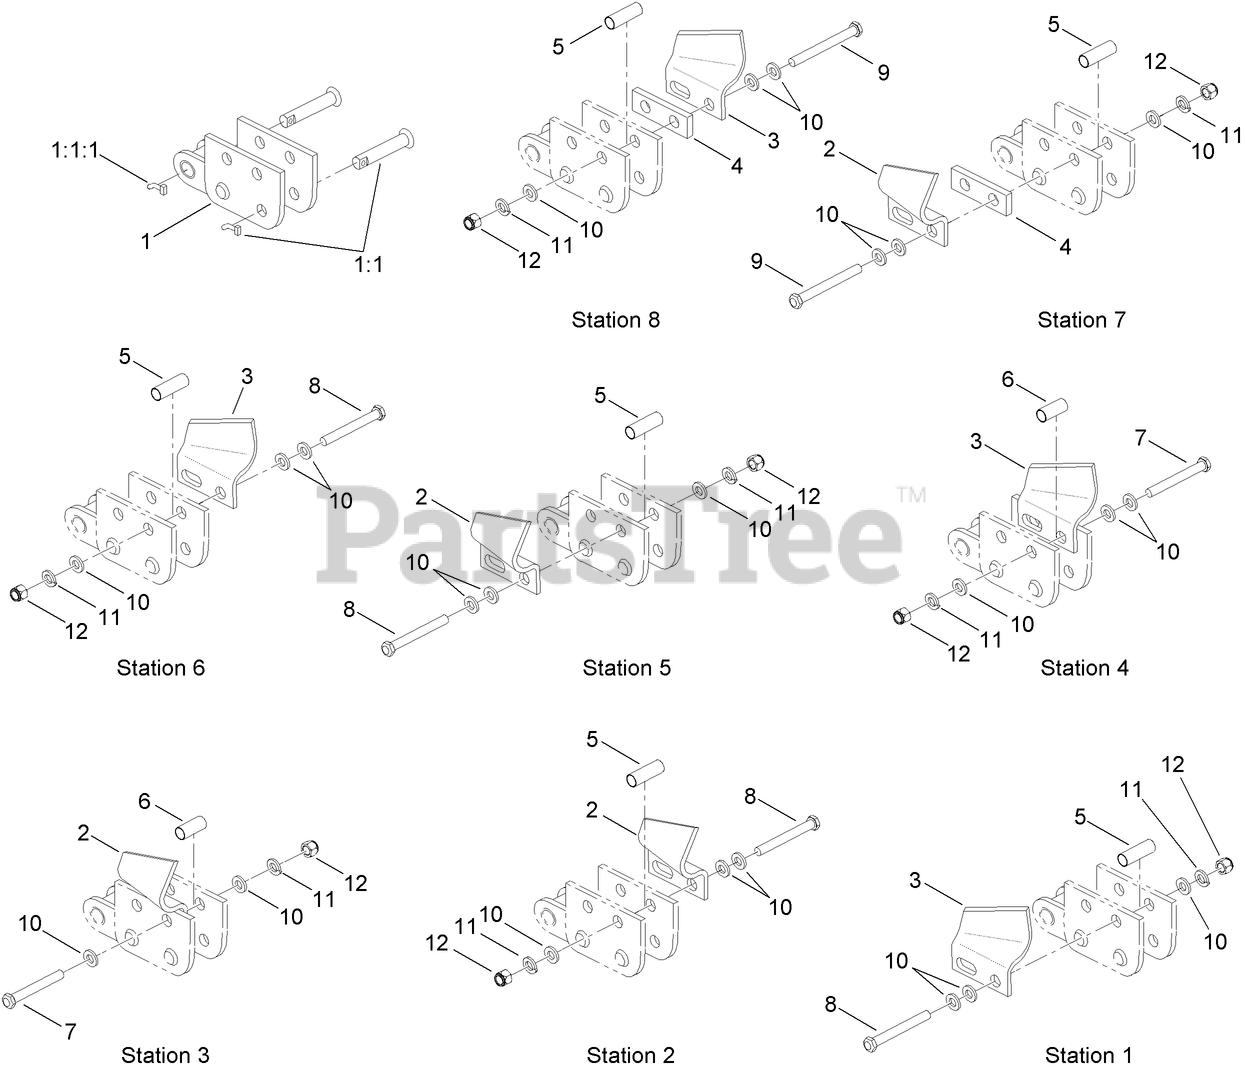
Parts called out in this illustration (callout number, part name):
1	CHAIN REPAIR LINK ASM
1:1	NOTCHED PIN AND KEEPER ASM
1:1:1	PIN-KEEPER
2	CUTTER-CUP, RH
3	CUTTER-CUP, LH
4	SPACER-FLAT
5	SPACER-TUBE, OUTSIDE MOUNT
6	SPACER-TUBE, INSIDE CUP MOUNT
7	BOLT-HH
8	BOLT-HH
9	BOLT-HH
10	WASHER-FLAT
11	WASHER-LOCK
12	NUT-LOCK
